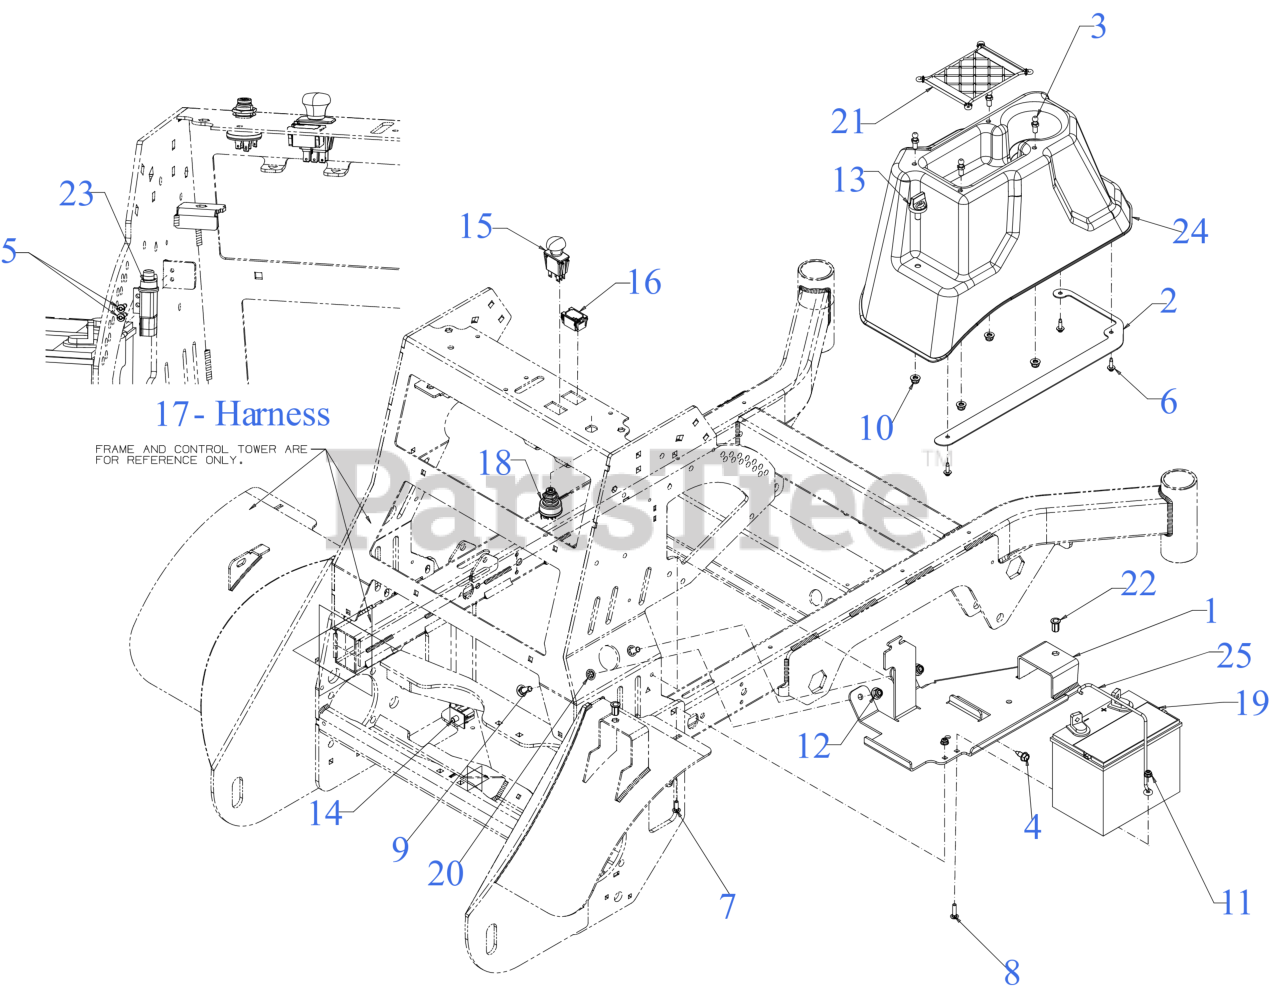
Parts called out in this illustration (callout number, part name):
1	BATTERY MOUNT BRACKET
2	BATTERY COVER SUPPORT PLATE
3	BALL STUD 5/16-18
4	SCREW 5/16-18 x .750
5	SCREW (10-24X.75:PH:TAP:T25:GR5)
6	SCREW 1/4-10 x .750
7	SCREW 1/4-20 x .75 GR5
8	SCREW 1/4-20 x 1 GR5
9	CARRIAGE BOLT 3/8-16 x 1.00 GR5
10	FLANGE LOCK NUT 5/16-18
11	FLANGE LOCK NUT
13	KNOB 3/8-16 x .875
14	NEUTRAL SWITCH
15	PTO SWITCH (BLACK KNOB) TEXT SYM
18	KEY SWITCH
18	PRO-Z KEY SET
19	Purchase Battery Locally
20	NUT:PUSH:3/8 ID x 3/4 OD
22	RIV NUT 3/8-16
23	SEALED PLUNGER SWITCH
24	BATTERY COVER
25	BATTERY SUPPORT ROD
